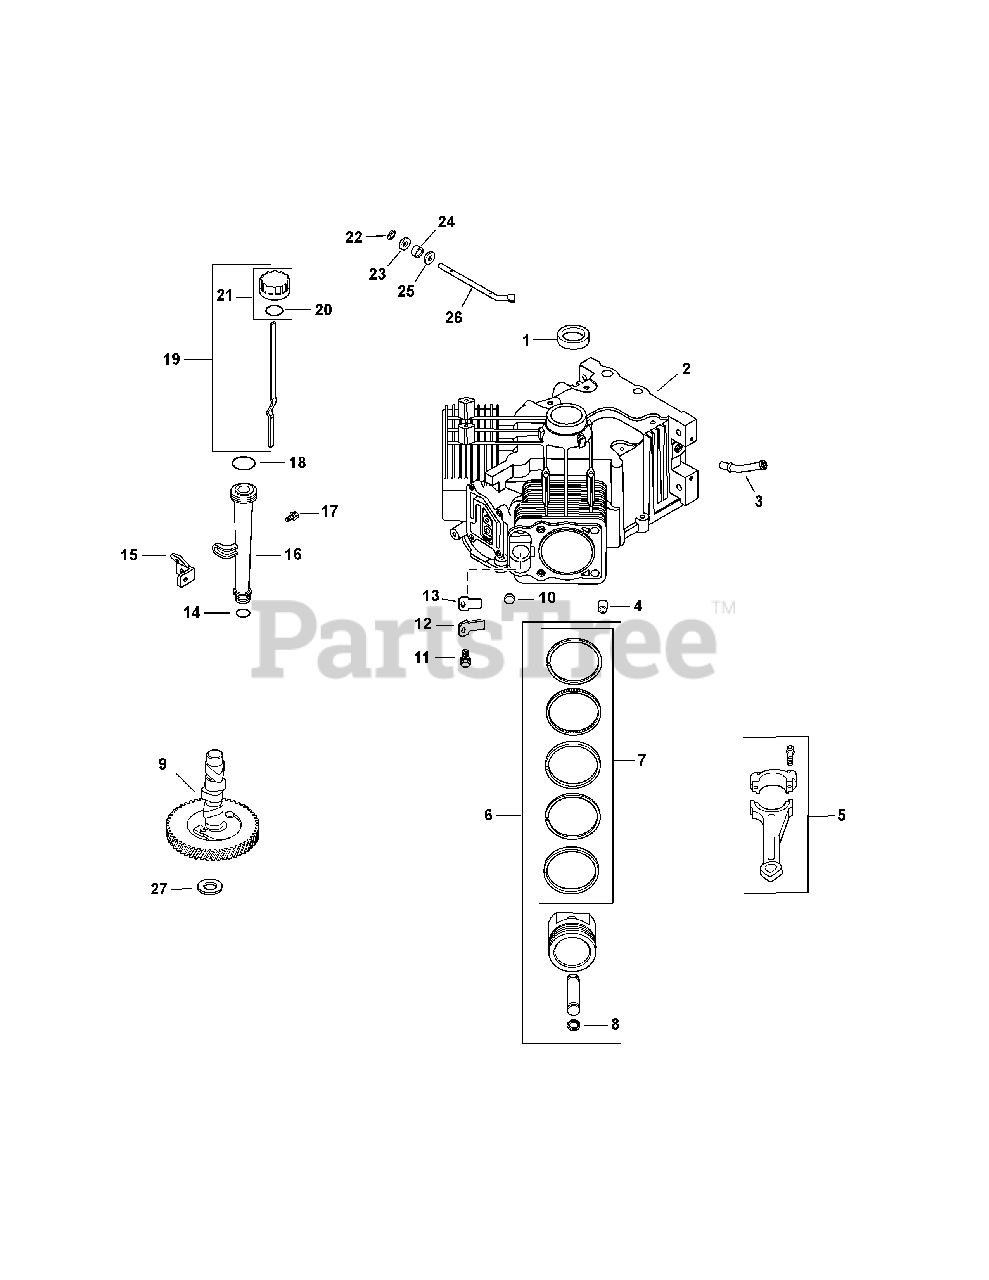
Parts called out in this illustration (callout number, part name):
1	SEAL, OIL (HELIX LIP)
2	CRANKCASE (USE SHORTBLOCK)
4	PIN, LOCATING
5	ROD, ASSEMBLY CONNECTING (STD)
5	ROD, ASSY CONNECTING (.25 O.S.)
6	KIT,PISTON W/RNG SET (STD) 83mm!
6	KIT,PISTON W/RING (0.08) 83mm
6	KIT,PISTON W/RING (0.25) 83mm
6	KIT,PISTON W/RING (0.50) 83mm
7	RING SET (STD)
7	RING SET (.08)
7	RING SET (.25)
7	RING SET (.50)
8	RETAINER, PISTON PIN
9	KIT, CAMSHAFT
11	SCREW, FLG THD FRM M5X.8X10
12	RETAINER, BREATHER REED
13	REED, BREATHER
14	O-RING, LOWER OIL FILL TUBE
15	BRACKET, OIL FILL TUBE
16	TUBE ASSEMBLY
17	SCREW, FLG THD FRM M5X0.8X16
18	O-RING, DIPSTICK
19	DIPSTICK, ASSY
20	O-RING, DIPSTICK
21	KIT, OIL FILL CAP (YELLOW)
22	RETAINER, RING
23	WASHER, FLAT 9 MM
24	SEAL, GOVERNOR CROSS SHAFT
25	WASHER, FLAT 11/32''
26	SHAFT, GOVERNOR CROSS
27	SHIM, CAMSHAFT (WHITE .028'')
